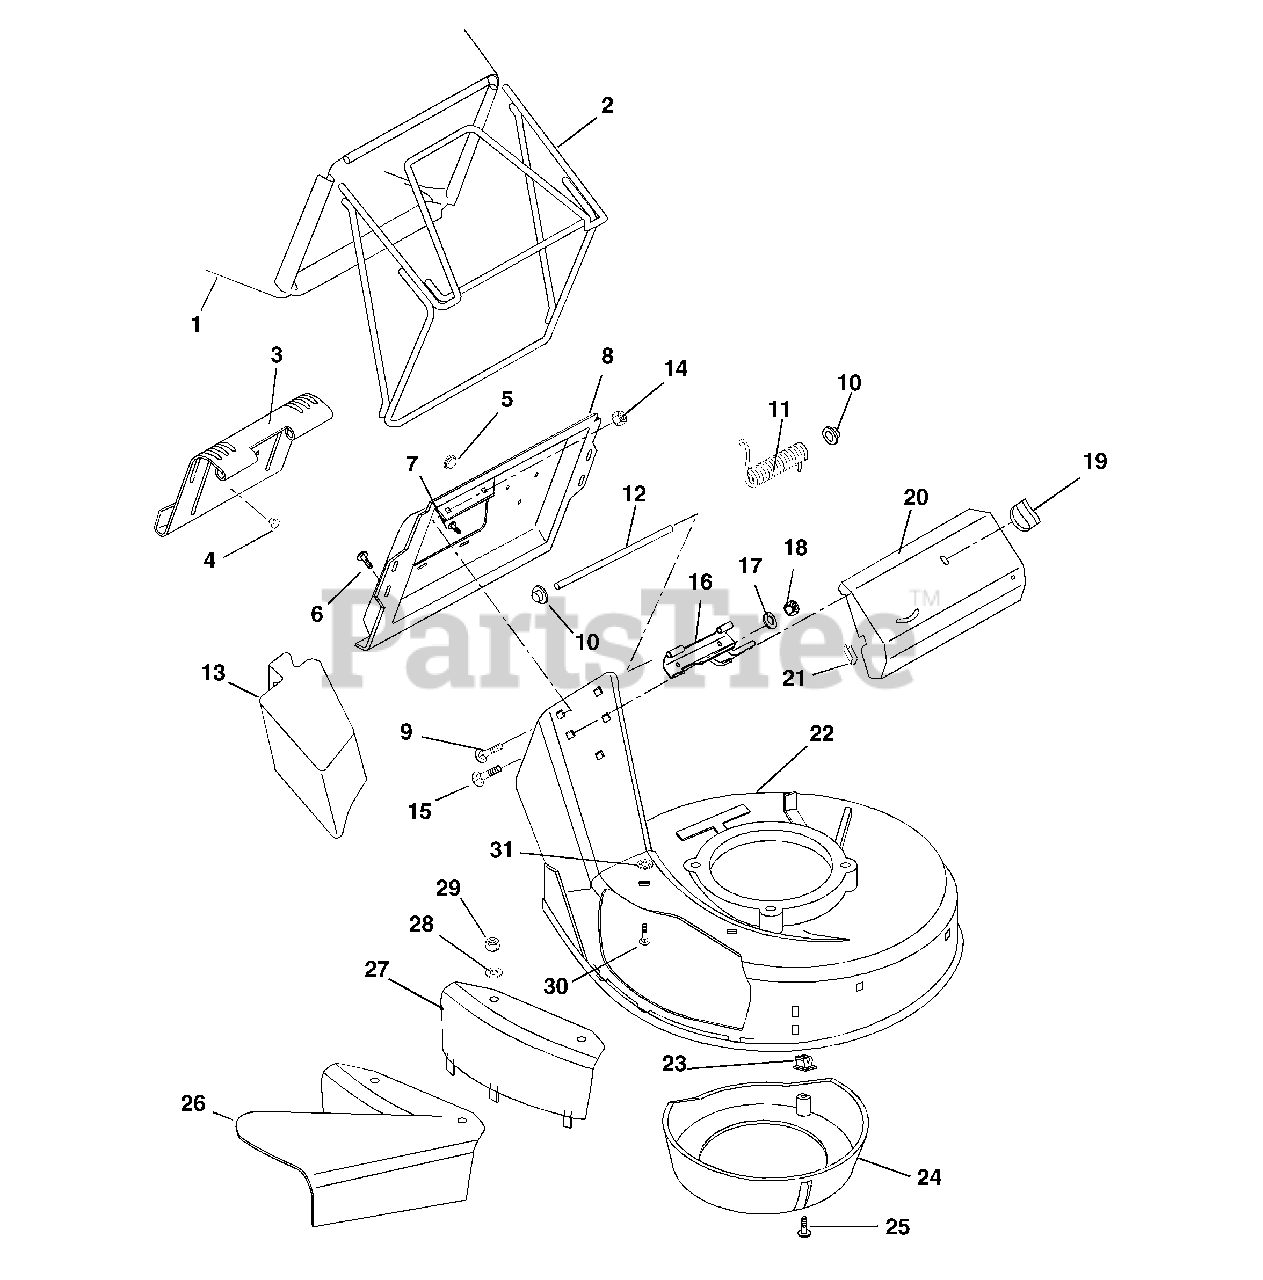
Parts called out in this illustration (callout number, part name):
1	BAG, GRASS MACK
2	FRAME, BAGGER
3	CATCHER PLATE DOOR
4	BUTTON BUMPER
6	@SCR-TAP 12-24X.50 HWH TR YWZC
7	SCR-TAP 10-24X.375 TORX PHD YZ
8	CATCHER PLATE
9	@BLT-RHDSSQNK .25-20X.38 G2YZ
10	PUSH NUT, .25
11	SG-TORS .120X.68X3.09
12	DOOR PIN
13	MULCH MASTER MULCHER ACCESSORY
14	@NUT-SPNLK-FLG .25-20 YWZC
15	@BLT-RDHDSQNK .25-20X.75 G5YZ
16	HINGE BASE WELDMENT
17	WSHR-LK .250X.077 HVY YWZC
18	@NUT-HEX .25-20 YWZC
19	WING - NUT
20	COVER, DRIVE
21	TRIM BUMPER
22	MOWER PAN W/SFTY DCLS MACK SP
23	PLASTIC GROMMET
24	CENTER BAFFLE
25	SCR-TAP 10-16X.62 SLPH AB YWZC
26	SIDE DISCHARGE ASSEMBLY
27	COVER, SIDE DISCHARGE
28	@WSHR-FL-STL.406X.812X.065 YWZ
29	@NUT-LK-NYL .312-18 YWZC
30	BLT-RDHDSQSHK.31-18X.75 GR2 YW
31	NUT-PUSH .312
